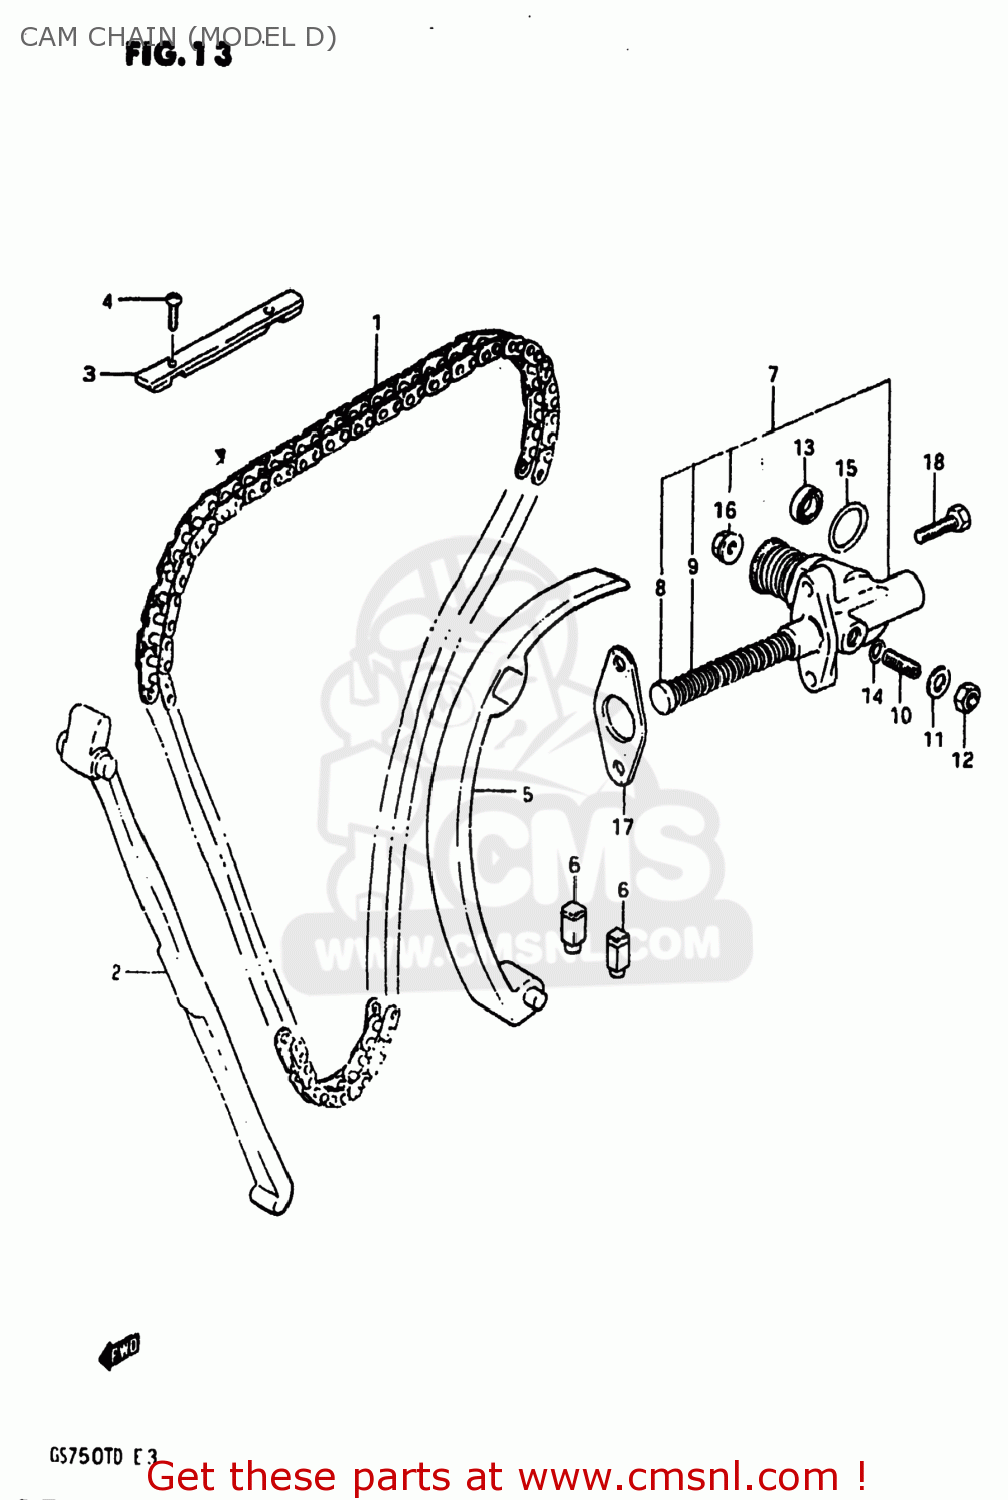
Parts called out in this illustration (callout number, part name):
1	CHAIN,CAMSHAFT DRIVE
2	GUIDE,CAM CHAIN NO.1
3	GUIDE,CAM CHAIN NO.3
4	SCREW
5	TENSIONER,CAM CHAIN
6	CUSHION,CAM CHAIN TENSIONER
7	ADJUSTER ASSEMBLY,TENSIONER
8	ROD,PUSH
9	SPRING
10	SCREW,TENSIONER ADJUST
11	WASHER,8.5X16X
12	NUT
13	SEAL,OIL(10X16X4)
14	O-RING
15	O RING(D:2.4,ID:20.8)
16	NUT
17	GASKET,TENSIONER ADJUSTER (MCA)
18	SCREW
